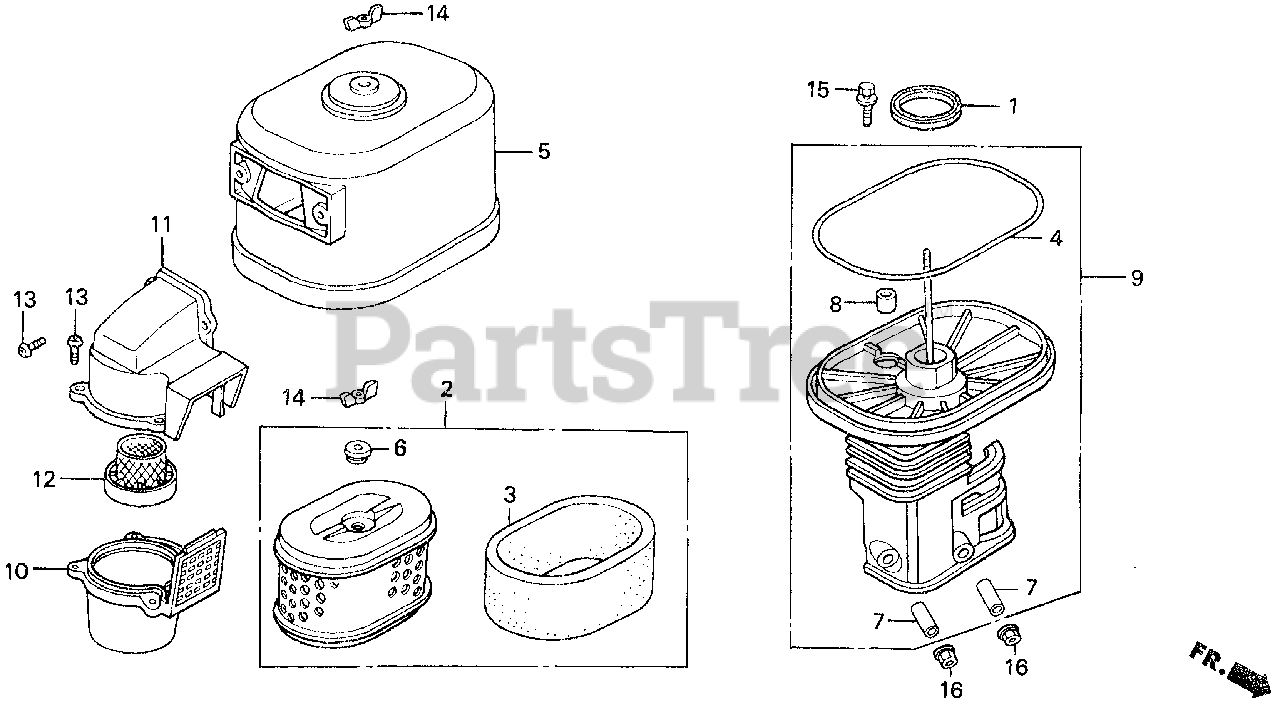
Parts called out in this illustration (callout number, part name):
1	GASKET, ELBOW
2	ELEMENT, AIR CLEANER
3	FILTER (OUTER)
4	SEAL, AIR CLEANER COVER
5	COVER, AIR CLEANER (CYCLONE)
6	GROMMET, AIR CLEANER
7	COLLAR, AIR CLEANER
8	COLLAR B, AIR CLEANER
9	ELBOW, AIR CLEANER
10	CASE, PRE AIR CLEANER
11	CAP, PRE AIR CLEANER
12	GUIDE, PRE AIR CLEANER
13	SCREW, PAN (5X16.5)
14	WINGNUT, TOOL BOX SETTING
15	BOLT-WASHER (6X20)
16	NUT, FLANGE (6MM)
